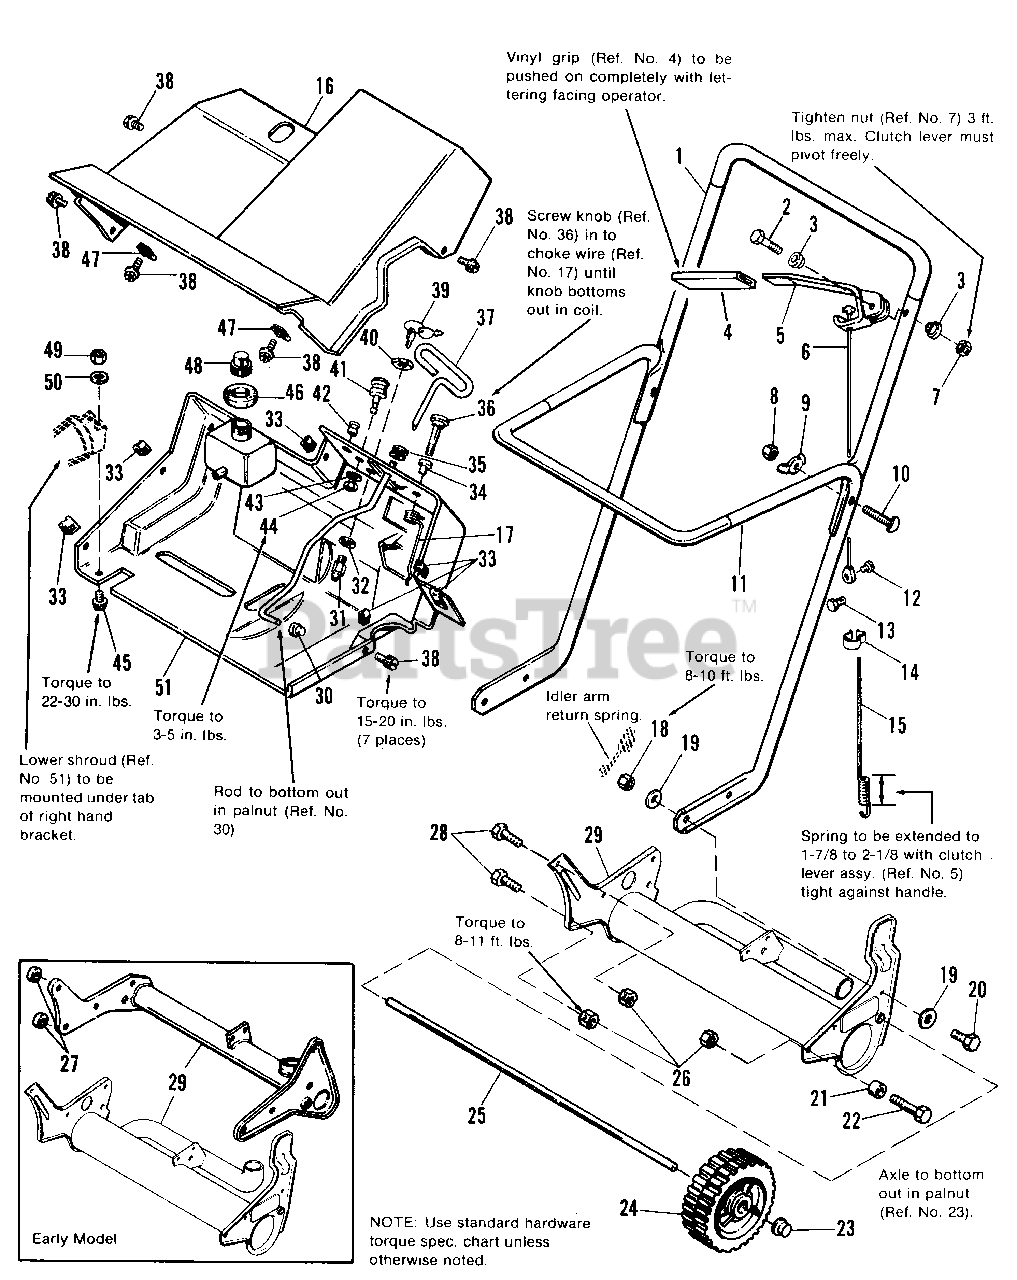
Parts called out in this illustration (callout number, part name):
1	HANDLE, Upper
2	CAPSCREW, Hex Hd., 1/4-20 x 1-3/4
2	MUFFLER KIT (1690357 before serial no. 12743)
2	MUFFLER ASSY. (1690357 after serial no. 12742)
4	GRIP, Handle
5	LEVER ASSY., Clutch
6	CABLE ASSY., Clutch Control
7	LOCKNUT, Hex, 1/4-20
8	NUT, Acorn, 5/16-18
9	NUT, Wing
10	BOLT, Curved Hd.
11	HANDLE, Lift
12	SCREW, Round Hd., #8-32 x 5/16
15	SPRING, Tension
16	SHROUD, Upper
17	WIRE, Choke Control
18	LOCKNUT, Plain, 1/4
19	WASHER, Plain, 1/4
20	CAPSCREW, Hex Hd., 1/4-20 x 7/8
21	SPACER, L.H.
22	CAPSCREW, Hex Hd., 5/16-18 x 1-1/2
23	PUSHNUT, 3/8
26	LOCKNUT, Hex, 5/16-18
27	SPACER, R.H.
28	CAPSCREW, Hex Hd., 5/16-18 x 3/4
29	MUFFLER KIT (1690354 before serial no. 29431)
29	MUFFLER ASSY. (1690354 after serial no. 29430)
30	PUSHNUT, 1/4
31	SWITCH, Ignition
32	LOCKWASHER, Int. Tooth, 5/8
33	NUT, Speed, "U", #10
34	GUIDE, Choke Knob
36	KNOB, Choke Control
37	ROD, Vane Control
38	SCREW, Hex Wash. Hd., Slotted, #10-24x5/8
39	KEY & RING ASSY., (2 Keys)
40	NUT, Ignition Switch
41	BULB, Primer
42	GUIDE, Starter Rope
43	LOCKWASHER, Ext. Tooth, 1/4
44	LOCKNUT, Hex, Jam, 1/4-20
45	SCREW, Hex Wash. Hd., Slotted, #10-24 x 5/8
46	WASHER, Foam
47	NUT, Speed "U", #10
48	CAP, Gas
49	LOCKNUT, Center, #10-24
50	WASHER, Plain, #10
51	SHROUD ASSY., Lower
